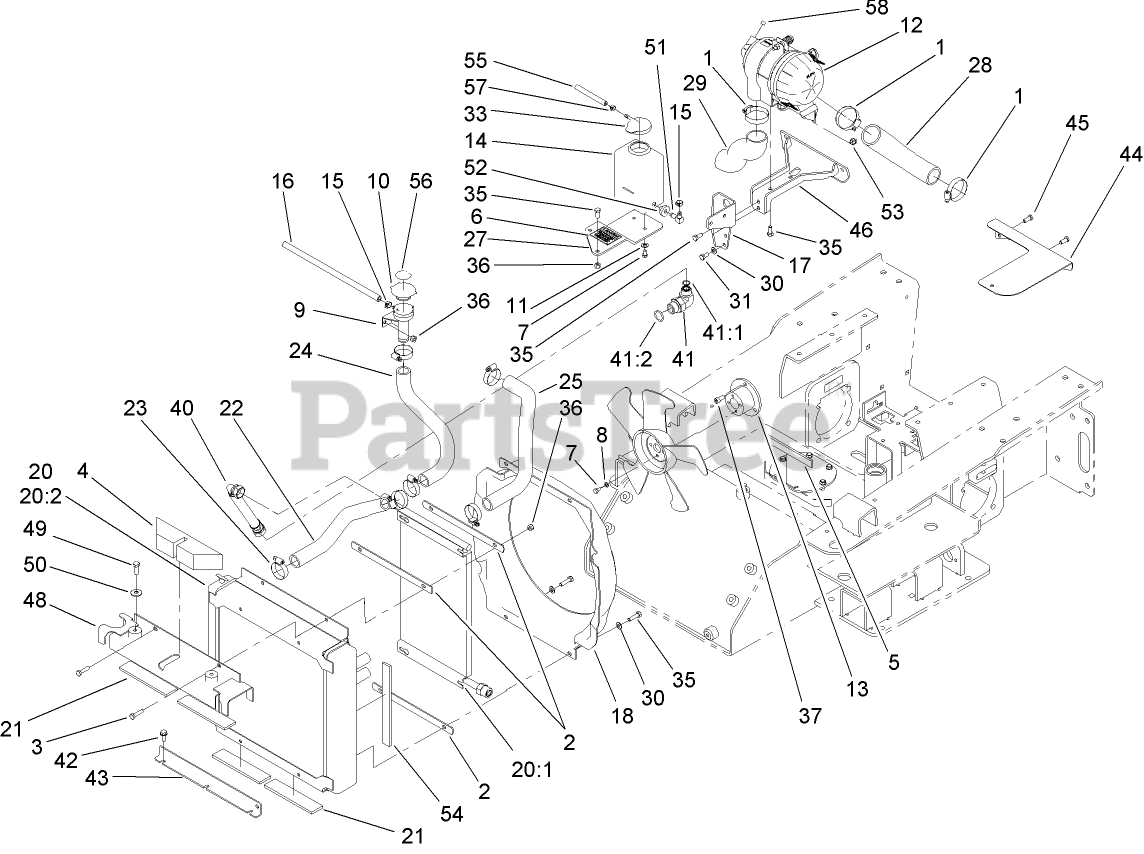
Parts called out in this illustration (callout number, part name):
1	CLAMP-HOSE
2	PLATE-BACKING
3	SCREW-HH
4	SEAL-FOAM
5	PAD-RUBBER
6	DECAL-RADIATOR, FILL
7	SCREW-HH
8	WASHER-LOCK
9	TUBE-FILLER, RADIATOR
10	CAP-RADIATOR
11	WASHER-FLAT
12	AIR CLEANER ASM
13	SPACER-FAN, MOUNT
14	TANK-OVERFLOW
15	CLAMP-HOSE
16	HOSE-LP
17	MOUNT-FILTER, AIR
18	SHROUD-FAN
20	RADIATOR AND OIL COOLER ASM
20:1	COOLER-OIL, HYD
20:2	RADIATOR
21	PAD-RUBBER
22	HOSE-RADIATOR
23	CLAMP-HOSE
24	HOSE-RADIATOR
25	HOSE-RADIATOR
27	BRACKET-TANK, OVERFLOW
28	HOSE-AIR, INLET
29	HOSE-AIR
30	WASHER-PLAIN
31	BOLT
33	CAP-TANK, OVERFLOW
35	SCREW-HH
36	NUT-LOCK, NI
37	SCREW-CAP, HSH
40	HYD HOSE ASM
41	FITTING-ELBOW 90
41:1	O-RING
41:2	O-RING
42	SCREW-HWHTF
43	MOUNT-RADIATOR
44	PLATE-BAFFLE, STARTER
45	SCREW-HH
46	BRACKET ASM
48	BRACKET-RADIATOR
49	SCREW-HH
50	WASHER-SPRING
51	FITTING-ELBOW
52	BUSHING-VALVE, FUEL
53	NUT-HF
54	FOAM-SEAL
55	HOSE-LP
56	DECAL-CAP, RADIATOR
57	CLAMP-HOSE
58	PLUG-PIPE
